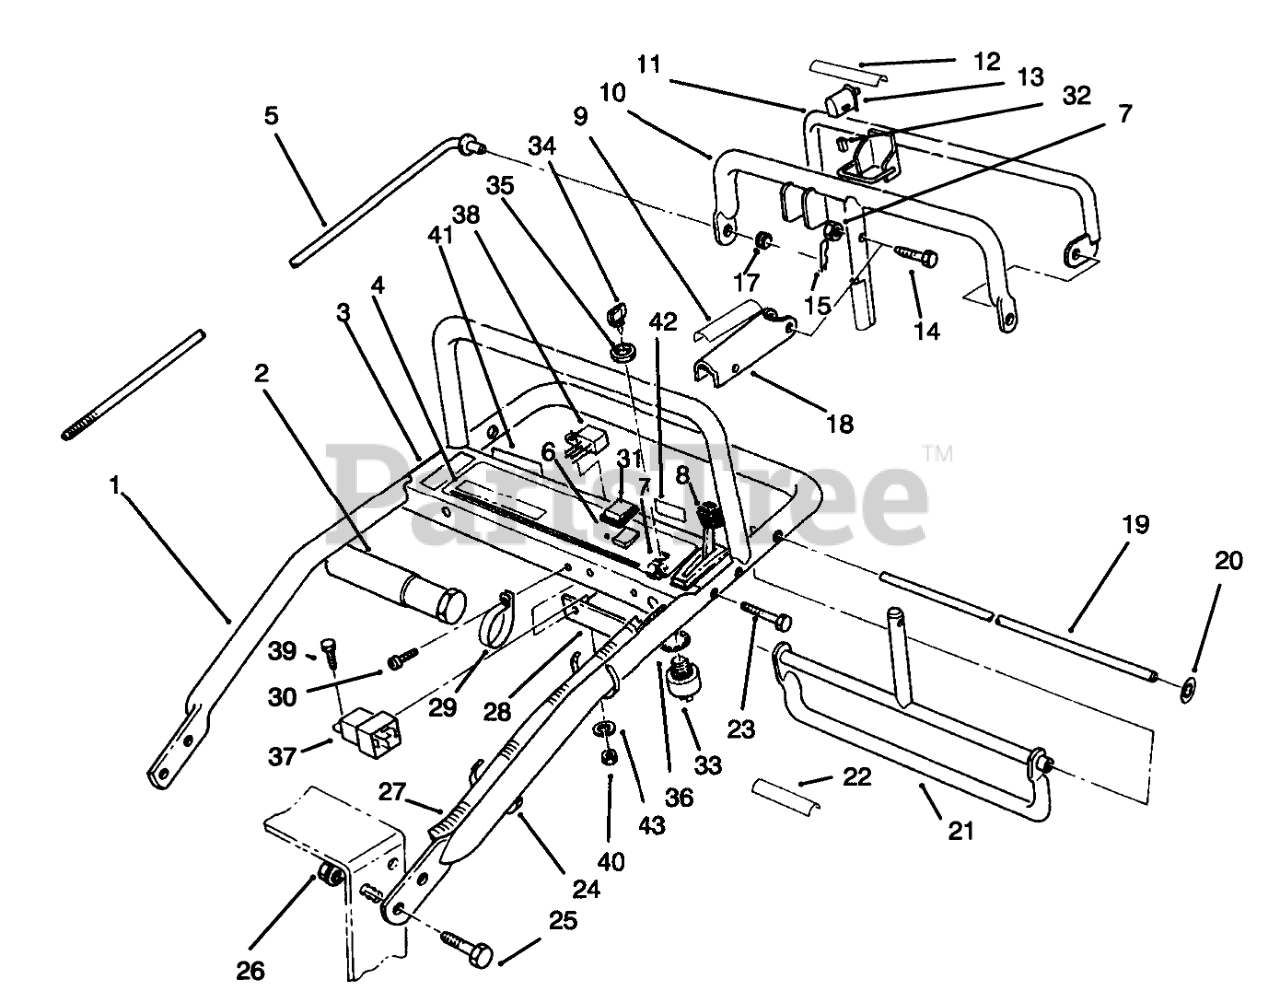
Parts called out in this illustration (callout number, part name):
1	Handle-Upper
2	TUBE-MANUAL
3	Panel-Control
4	DECAL-CONTROL PANEL
5	ROD-CONTROL
6	SWITCH
7	NUT-LOCK, NI
8	CONTROL-THROTTLE
9	DECAL-LEVER, PARKING
10	Bar
11	Bail
12	DECAL
13	SWITCH-BAIL
14	SCREW-SHH
15	PIN-COTTER
17	GROMMET-RUBBER
18	Lever-Parking Brake
19	PIVOT ROD
20	NUT-PUSH-ON, CIRCULAR
21	Control Pivot
22	DECAL
23	SCREW-SHH
24	TIE-CABLE
25	SCREW-HHF
26	NUT-HF
27	WIRE HARNESS
28	Panel-Bottom
29	CLAMP-R
30	SCREW-SHWH
31	BOOT-SWITCH
32	CONNECTOR-BODY
33	Switch-On/Off (Incl. Ref. #34-36)
34	KEY-IGNITION
35	NUT-HH
36	WASHER-TOOTH, INTERNAL
37	RELAY
38	Module
39	SCREW-HH
40	NUT-LOCK, NI
41	DECAL-INSTRUCTION, SAFETY
42	DECAL-INSTRUCTION
43	WASHER-LOCK/EXT
